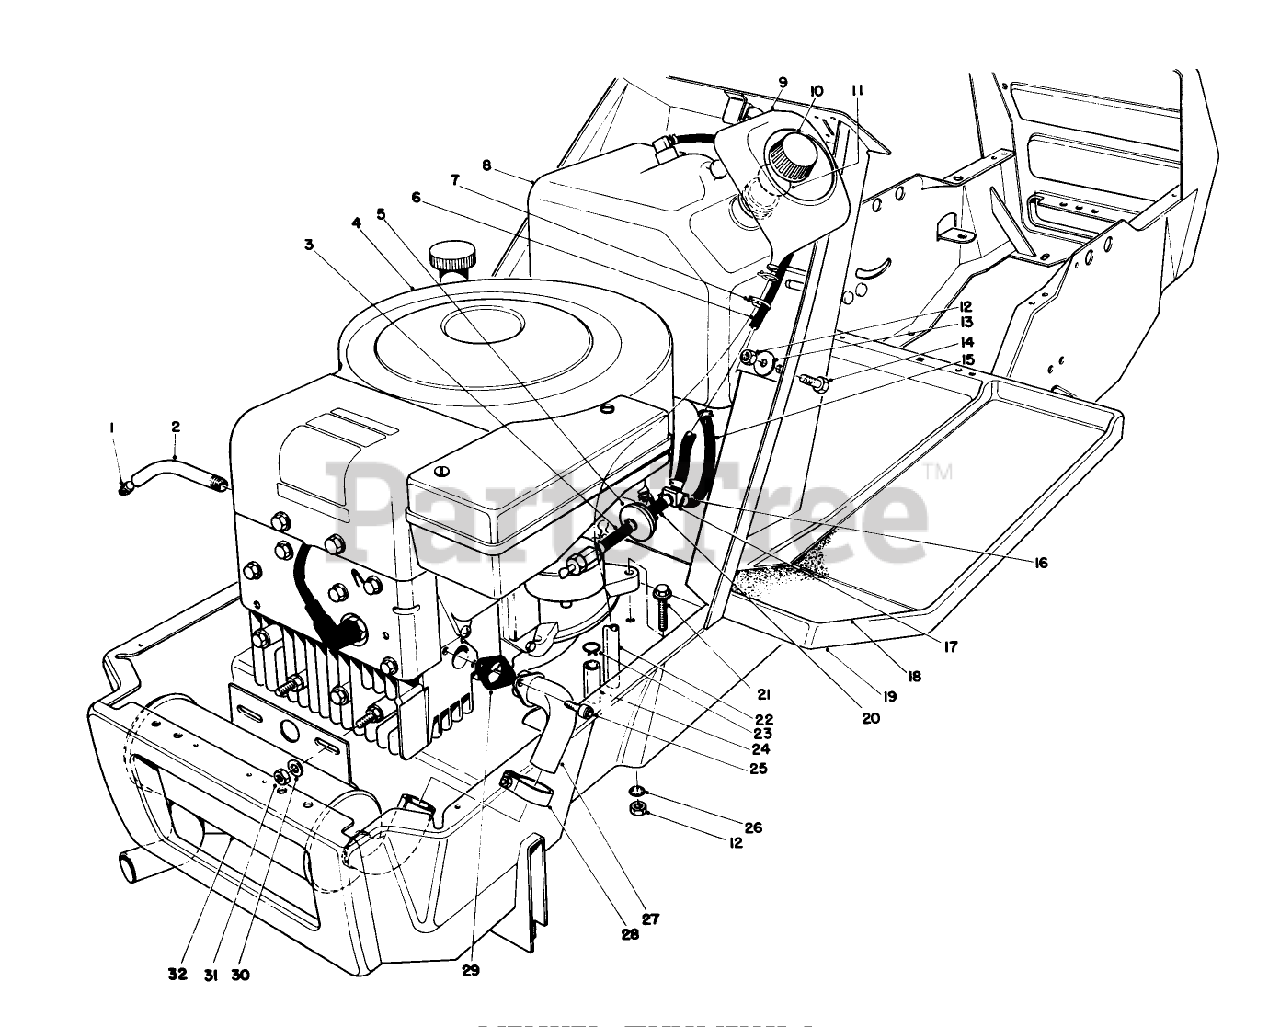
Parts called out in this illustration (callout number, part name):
1	PLUG-PIPE, SQH
3	Hose-Gas
4	Engine
5	Fuel Filter
7	TIE-CABLE
9	Funnel-Overflow
11	GAS CAP GASKET
12	NUT-LOCK, NI
14	SCREW-HH
16	FUEL HOSE CLAMP
21	SCREW-HH
22	Hose Funnel
25	SCREW-HSH
26	WASHER-LOCK, INTERNAL
29	Exhaust Gasket
30	WASHER-PLAIN
31	NUT-LOCK, CONE
32	EXHAUST MUFFLER 10 HP
